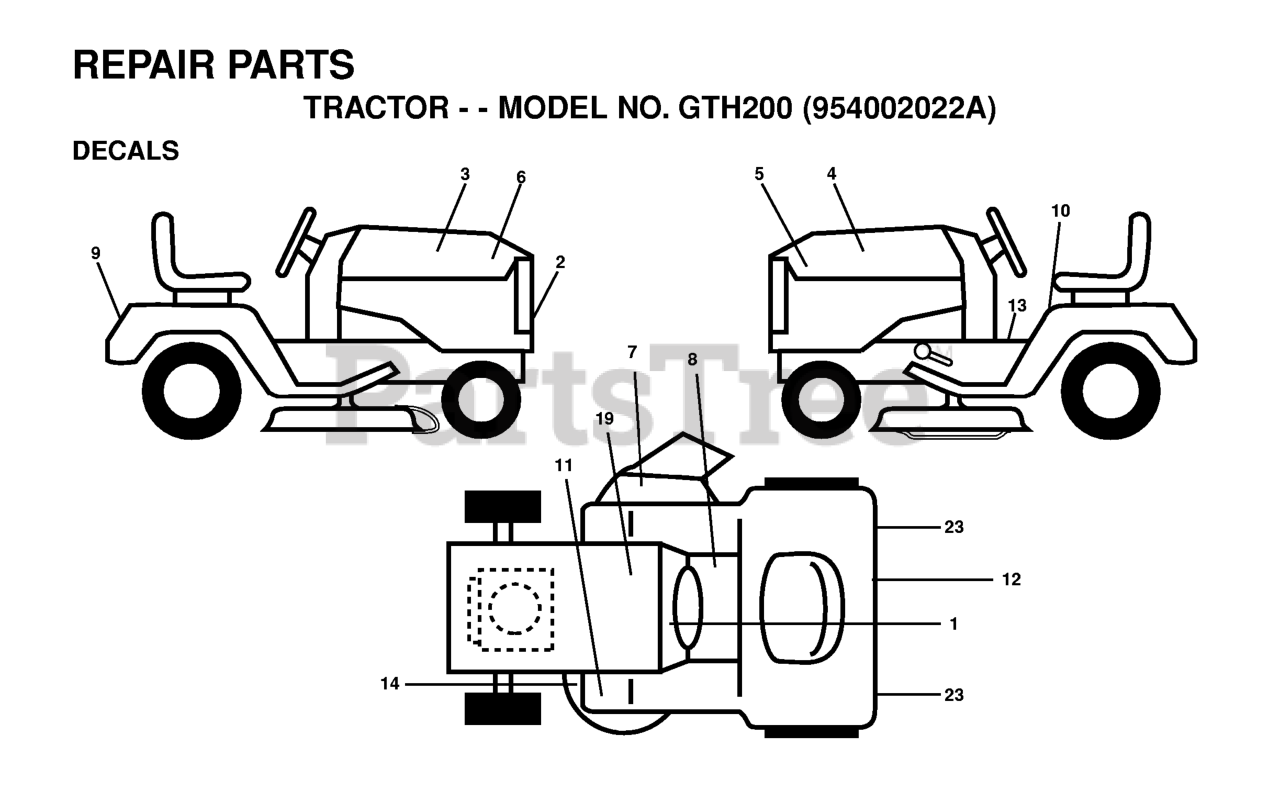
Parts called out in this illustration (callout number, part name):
2	DECAL GRILL HUSQ NLA
3	DECAL-HOOD R.H.
4	DECAL-HOOD L.H.
5	DECAL HOOD LH
6	DECAL HOOD RH
7	DECAL WARNING (ENGLISH/FRENCH)
8	DECAL PARK BRAKE
9	DECAL FENDER NLA
10	DECAL CAUTION
12	DECAL D-BAR
19	DECAL BTRY SYMBOLS
23	REFLECTOR-TAIL YT
